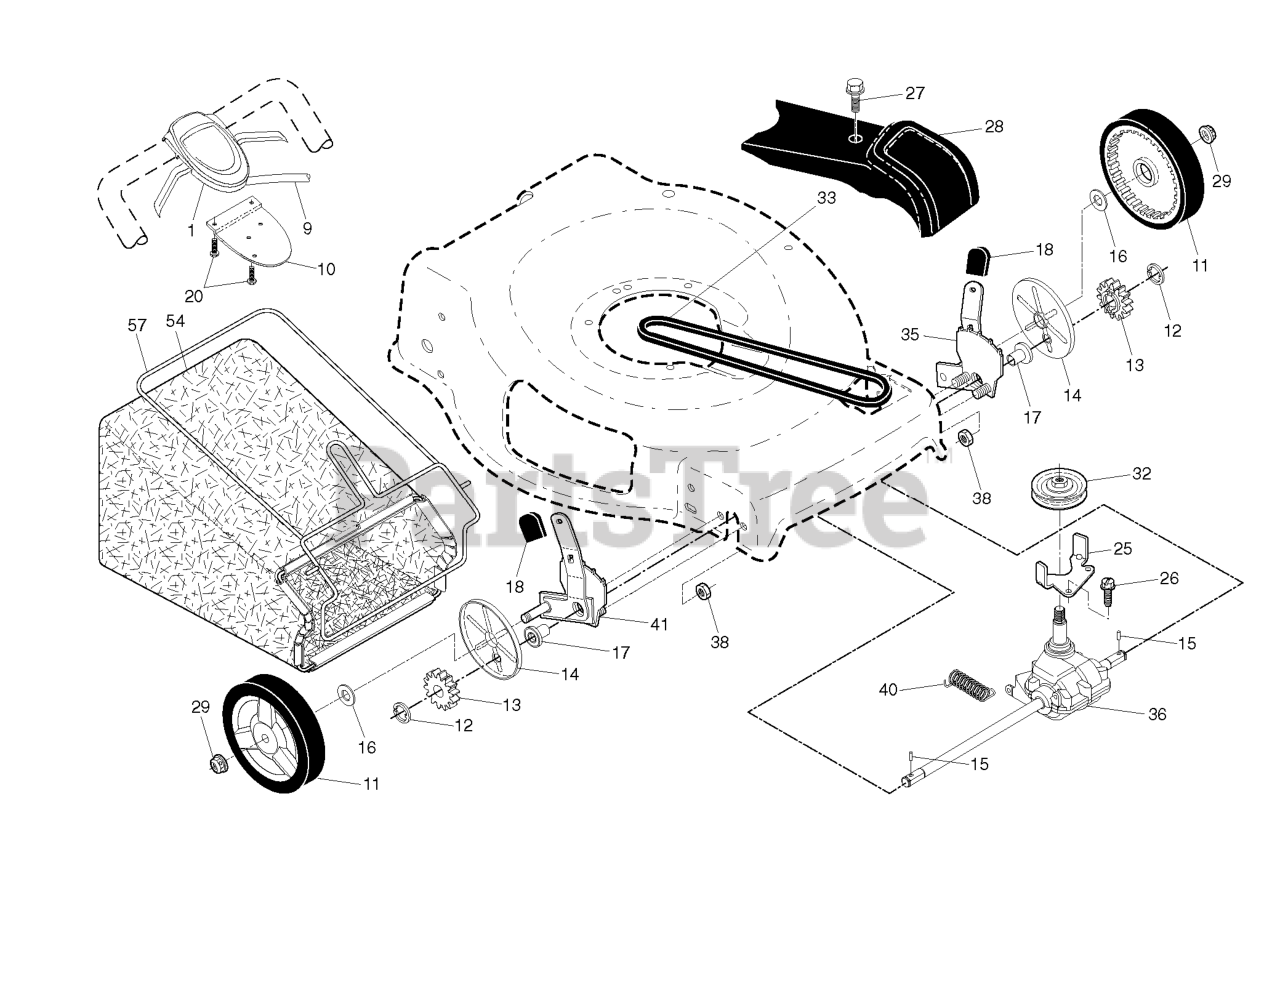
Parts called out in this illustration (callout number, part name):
1	CONTROL.AW2.22FGD.STR.GRY/BLK
9	CABLE.CONTROL.22FGD.GEN2
10	BRACKET.DRIVE.CONTR.GEN2.BLACK
11	WHEEL.8X1.75.H3SPK.RAD3.GY.BU3
12	E-RING 7/16 RE
13	PINION.14.TEETH.FGD
14	COVER.DUST.WHEEL.INNER.WALK
15	PAWL, DRIVE
16	WASHER FLUT
17	BEARING.ASM.
18	SELECTOR KNOB
20	SCREW, PHILLIPS HEAD 10 X 5/8
25	BRACKET.BELT.GUIDE.22+FGD.BZP
27	SCREW, HEX HD TAPPING #10-24 1
28	COVER.DRIVE.22.LABEL.HUSQVARNA
29	NUT.HEX.FLANGE.3/8-16.LO(3 2)
32	RP PULLEY.DRIVE.EZ/VAR.SCREWON
33	BELT.DRIVE.FWD.
35	ADJUSTER.ASM.9.22+/RF/LR.21/RF
36	TRANSMISSION.22PLUS.FGD.AW2/EZ
38	NUT.HEX.FLANGE.1/4
41	ADJUSTER.ASM.9.22+/RF/LR.21/LF
54	GBAG.A3610247T.SILV.HUSWT.BLUE
57	RB FRAME.GBAG.22PLUS
